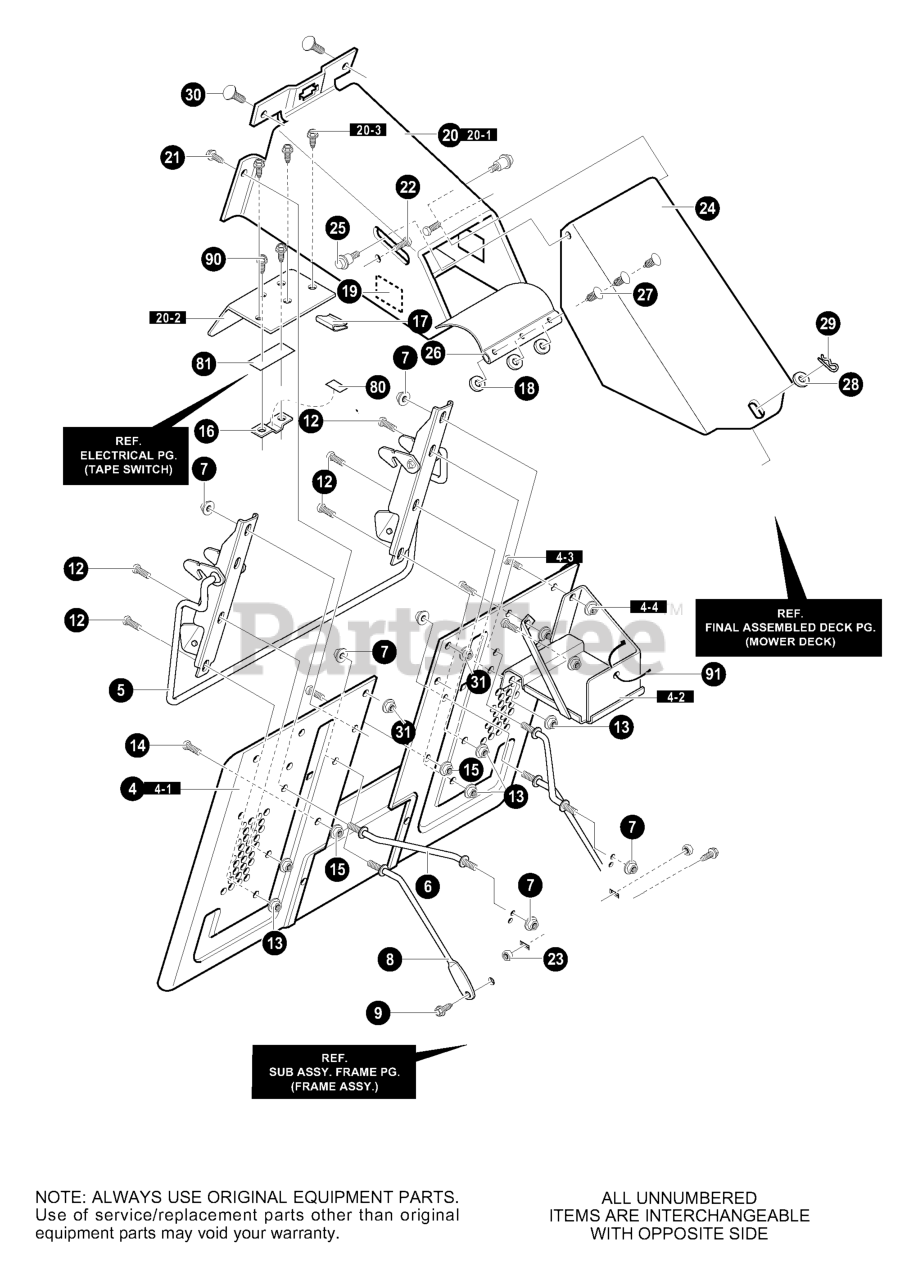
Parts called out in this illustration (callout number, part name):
4	ASSY, BACK PLATE/BATTERY
4-1	ASM. BACKPLATE FLAT
4-2	BATTERY TRAY ASM.
4-3	SCREW, 5/16-18 x 0.50 HHC
4-4	NUT, 5/16-18 HEXWDFLLK WHIZ
5	WELDMENT - LATCH LEVER
6	ROD, BRACE
7	NUT, 3/8-16 HWDFL WHIZ-LOCK
8	ROD, BRACE
9	SCREW, 5/16-18 x 0.75 HHWATAP
12	SCREW 5/16-18X.75 HXWDFL
13	NUT, 5/16-18 HEXWDFLLK WHIZ
14	SCREW 5/16-18X.75 HHWATAP
15	NUT, 5/16-18 HEXWDFLLK WHIZ
16	BRACKET, FLEX SWITCH MOUNTING
17	WIRE CLIP, ADHESIVE
18	FLATWASHER, .250X.56X.047
19	PAD, ADHESIVE 1.00X1.50X.12
20	ASM., T/A SHIELD & UPPER CHUTE
20-1	CHUTE WELD ASM. UPPER
20-2	SHIELD, TRANSAXLE
20-3	SCREW, 1/4-20X.63 HHWATAP
21	SCREW, 5/16-18 x.75 HHC
22	BOLT, 5/16-18X.75 CARR
23	NUT, 5/16-18 HEXWDFLLK WHIZ
24	MIDDLE CHUTE ASSY
25	BOLT, SHOULDER
26	FLAP, CHUTE
27	FASTENER, RATCHET
28	FLATWASHER
29	PIN, HAIR .38DIAX1.64LG
30	BOLT, 5/16-18X.75 CARR.
31	NUT, 5/16-18 HEXWDFLLK WHIZ
80	TAPE, DOUBLE SIDED FOAM 3/4" WD
81	TAPE, DOUBLE SIDED FOAM 3/4" WD
90	SCREW, 1/4-20X.63 HHWATAP
91	CABLE TIE
